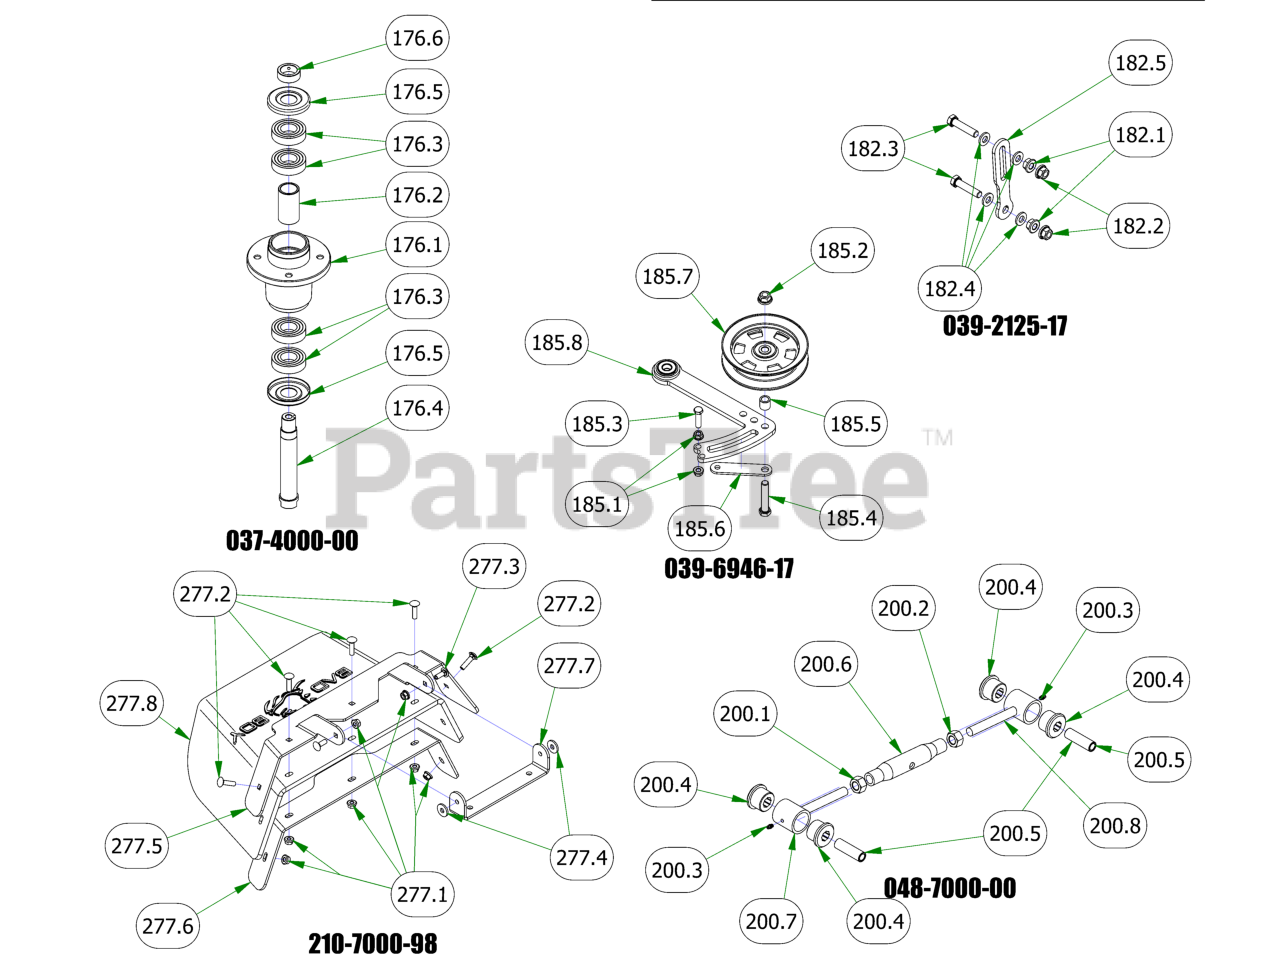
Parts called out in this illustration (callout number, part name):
176	OUTLAW SPINDLE ASSEMBLY
176.1	4000 Series Spindle Housing
176.2	4000 Series Spindle Spacer
176.3	Bearing - 6206
176.4	Spindle Shaft
176.5	Spindle Dust Cap
176.6	Locking Collar w/ 1/4"-20 Set Screw
182	Deck Hanger Assembly
182.1	1/2-13 HEX SERRATED FLANGE NUT HARD/ZINC
182.2	1/2-13 NYLON INSERT FLANGE LOCKNUT ZINC
182.3	1/2-13 X 2-1/4 HEX CAP SCREW (GR.5) ZINC
182.4	.505 ID X 1.000 OD X .125 THICK FLAT WASHER NYLON
182.5	Deck Hangar
185	2019 Renegade Deck Idler
185.1	3/8-16 HEX SERRATED FLANGE NUT HARD/ZINC
185.2	1/2-13 NYLON INSERT FLANGE LOCKNUT ZINC
185.3	3/8-16 X 1-1/2 HEX CAP SCREW (GR.5) ZINC
185.4	1/2-13 X 2-3/4 HEX CAP SCREW (GR.5) ZINC
185.5	.51 ID X .75 OD X .75 LGTH SOLID SPACER ZINC
185.6	Belt Tensioner Retainer Plate
185.7	5" Idler Pully
185.8	2019 Deck Tensioner
200	Turnbuckle
200.1	11/16-12 Hex Nut-2015 Toplink
200.2	11/16-12 Lefthand Hex Nut-Topl
200.3	1/4" Press in Grease Fitting
200.4	Polyeurethane Bushing
200.6	2015 Outlaw Toplink Body
200.7	2015 Outlaw Toplink RH End
200.8	2015 Outlaw Toplink LH End
277	2019 Outlaw Gen2 Chute Assembly
277.1	5/16-18 NYLON INSERT FLANGE LOCKNUT ZINC
277.2	5/16-18 X 1-1/4 CARRIAGE BOLT ZINC
277.3	5/16-18 X 7/8 CARRIAGE BOLT ZINC
277.4	.360 ID X .983 OD X .120 THICK FLAT WASHER NYLON
277.5	2019 Upper Chute Bracket
277.6	2019 Lower Chute Bracket
277.7	2019 Chute Hanger
277.8	2019 Belted Chute with Logo
